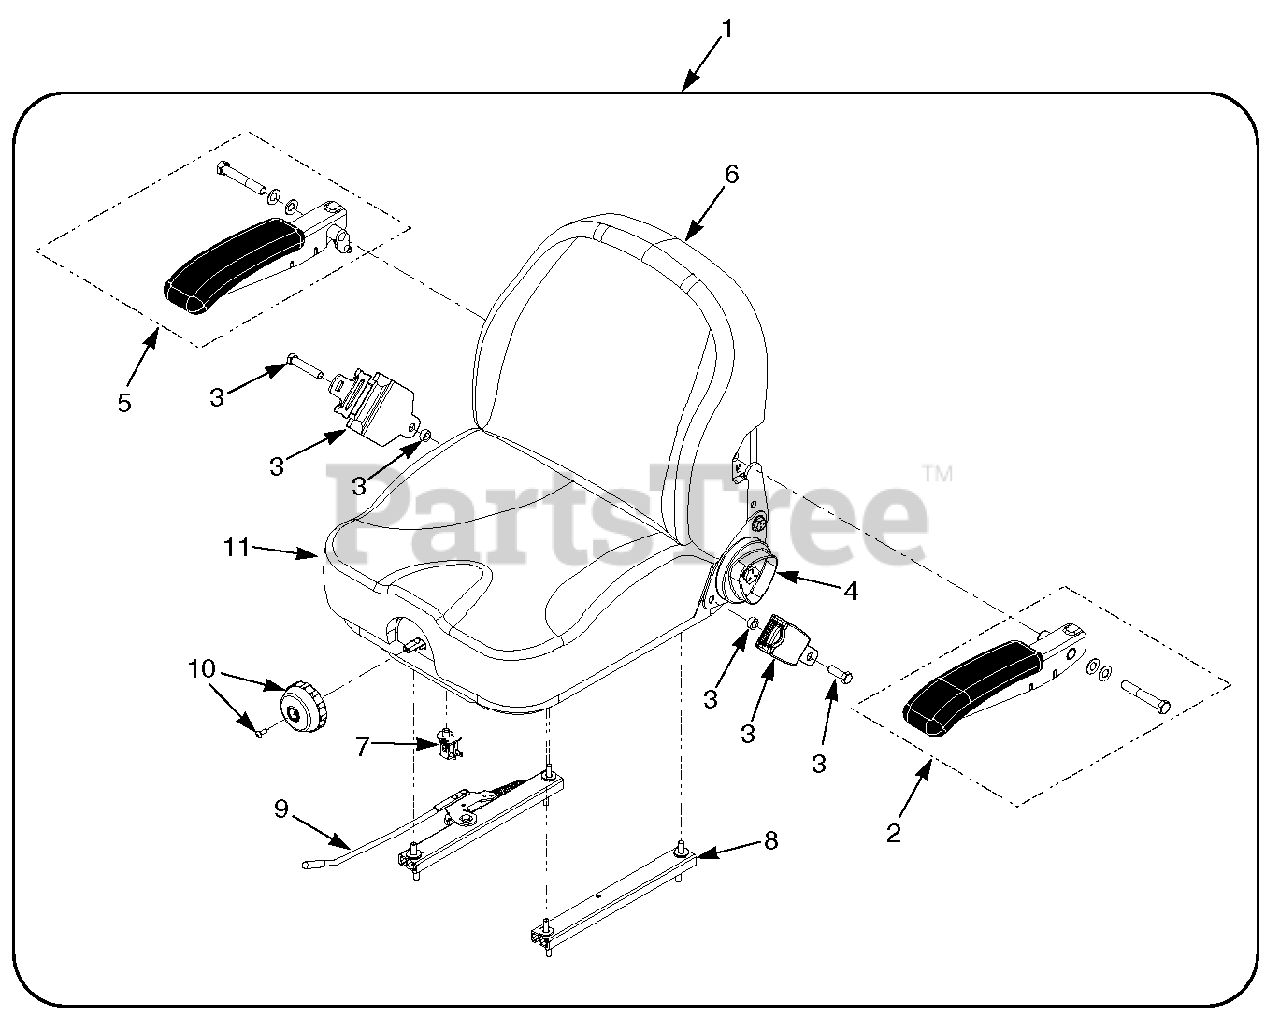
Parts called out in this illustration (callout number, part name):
1	Seat Assembly
2	Armrest Kit, LH
3	Seat Belt Kit
4	Knob Kit, Recliner
5	Armrest Kit, RH
6	Back Cover
7	Switch, N/O
8	Track Kit
9	Handle, Seat Track
10	Knob Kit, Weight Adjust
11	Cover, Seat Cushion
